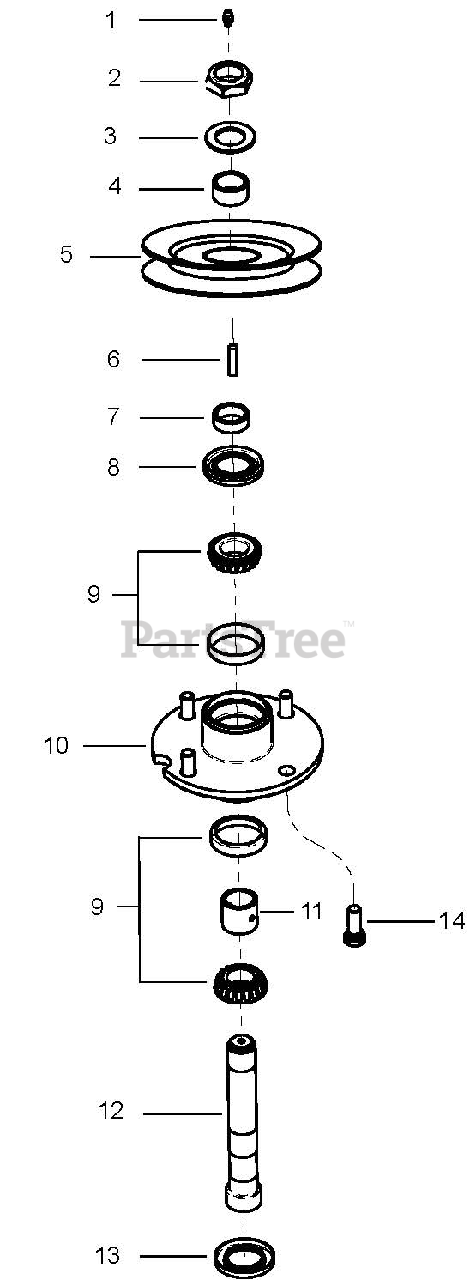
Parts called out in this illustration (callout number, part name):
1	FTG, 1/4-28 STRGT GREASE ZERK
2	NUT, 1-14 THIN PATTERN NYLOCK
3	WASHER, 1.062X1.75X0.100 Y
4	SPACER, ?1.01 X ?1.25 X .635 Y
5	PULLEY, BOTTOM
5	PULLEY, V-BELT 5.73X1.00 W/KEY
5	PULLEY, V-BELT 6.57X1.00 W/KEY
5	PULLEY, V-BELT 7.21X1.00 W/KEY
6	KEY, .250 X .250 X 1.00 SQ
7	BSHG, 1.00 X 1.25 X .438
8	SEAL, UPPER SPINDLE
9	BRG ASSY, 1IN DIA SPINDLE
10	CASTING-MOWER SPINDLE 3.31 LG
11	SPACER, BEARING
12	SHAFT, BLADE SPINDLE 1" LONG
12	SHAFT, BLADE SPINDLE 1" SHORT
13	SEAL, BRG 1.00 ROLLER
14	BOLT, 7/16-20X1.22 SPC 5 Y
15	ASSY, SPINDLE 1" LONG SHFT S/O
16	ASSY, SPINDLE 1"SHORT SHFT S/O
17	SPINDLE BEARING KIT
